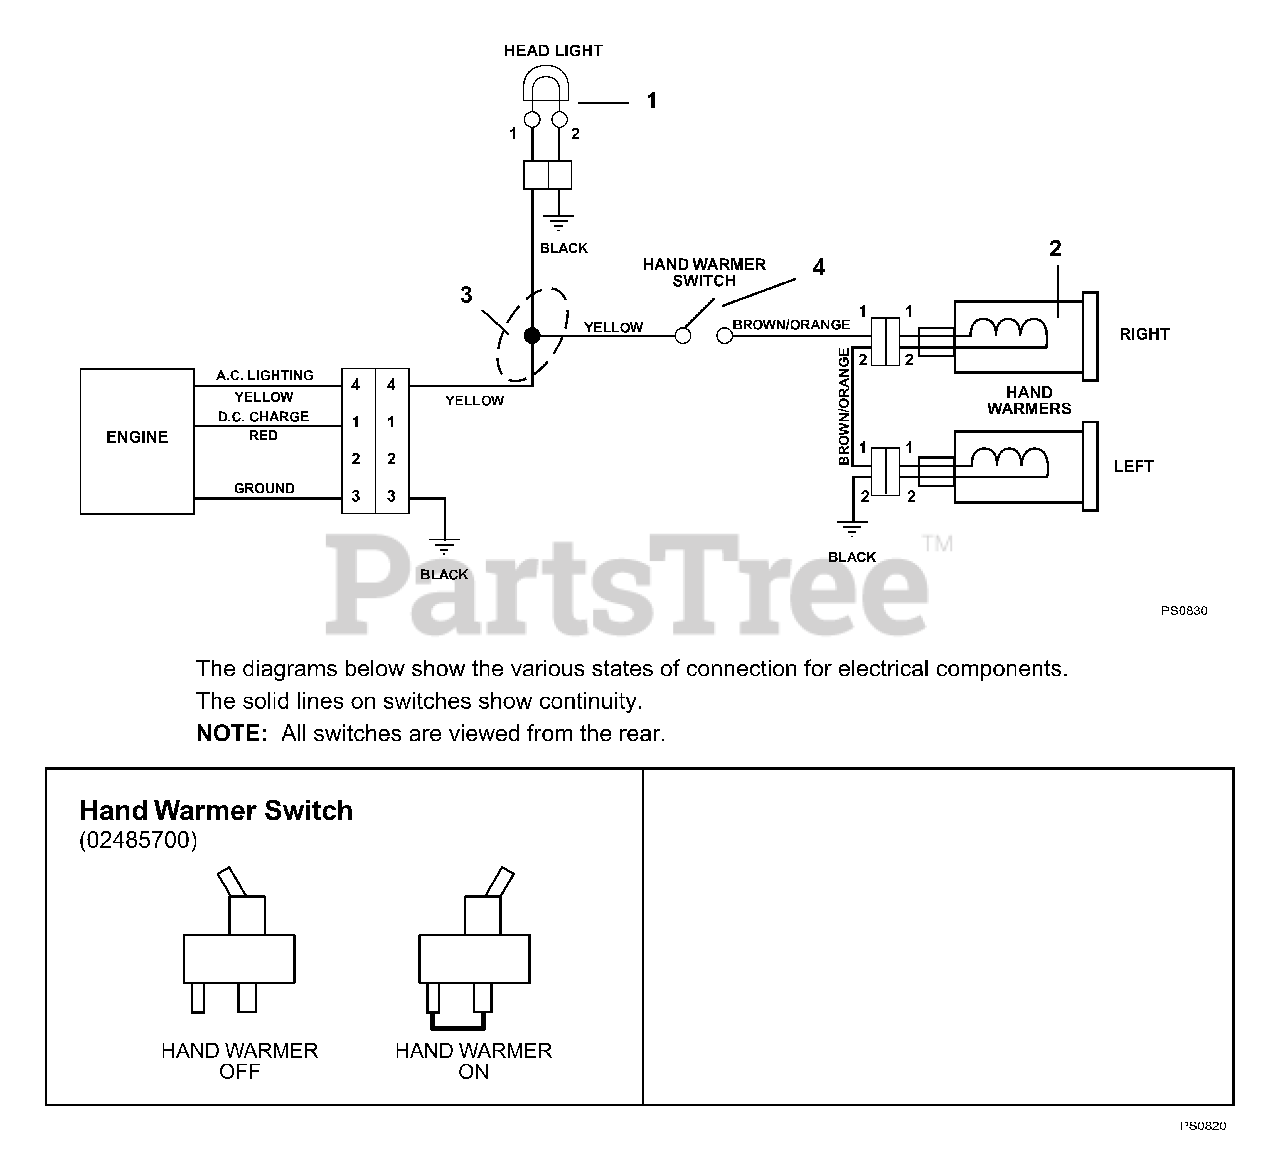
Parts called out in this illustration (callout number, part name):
1	Light, Halogen Assembly
2	Warmer, Hand with Terminal
3	Wire Harness-Hand Warmer and Light
4	Switch, On/Off Hand Warmer
02485700	Hand Warmer Switch
